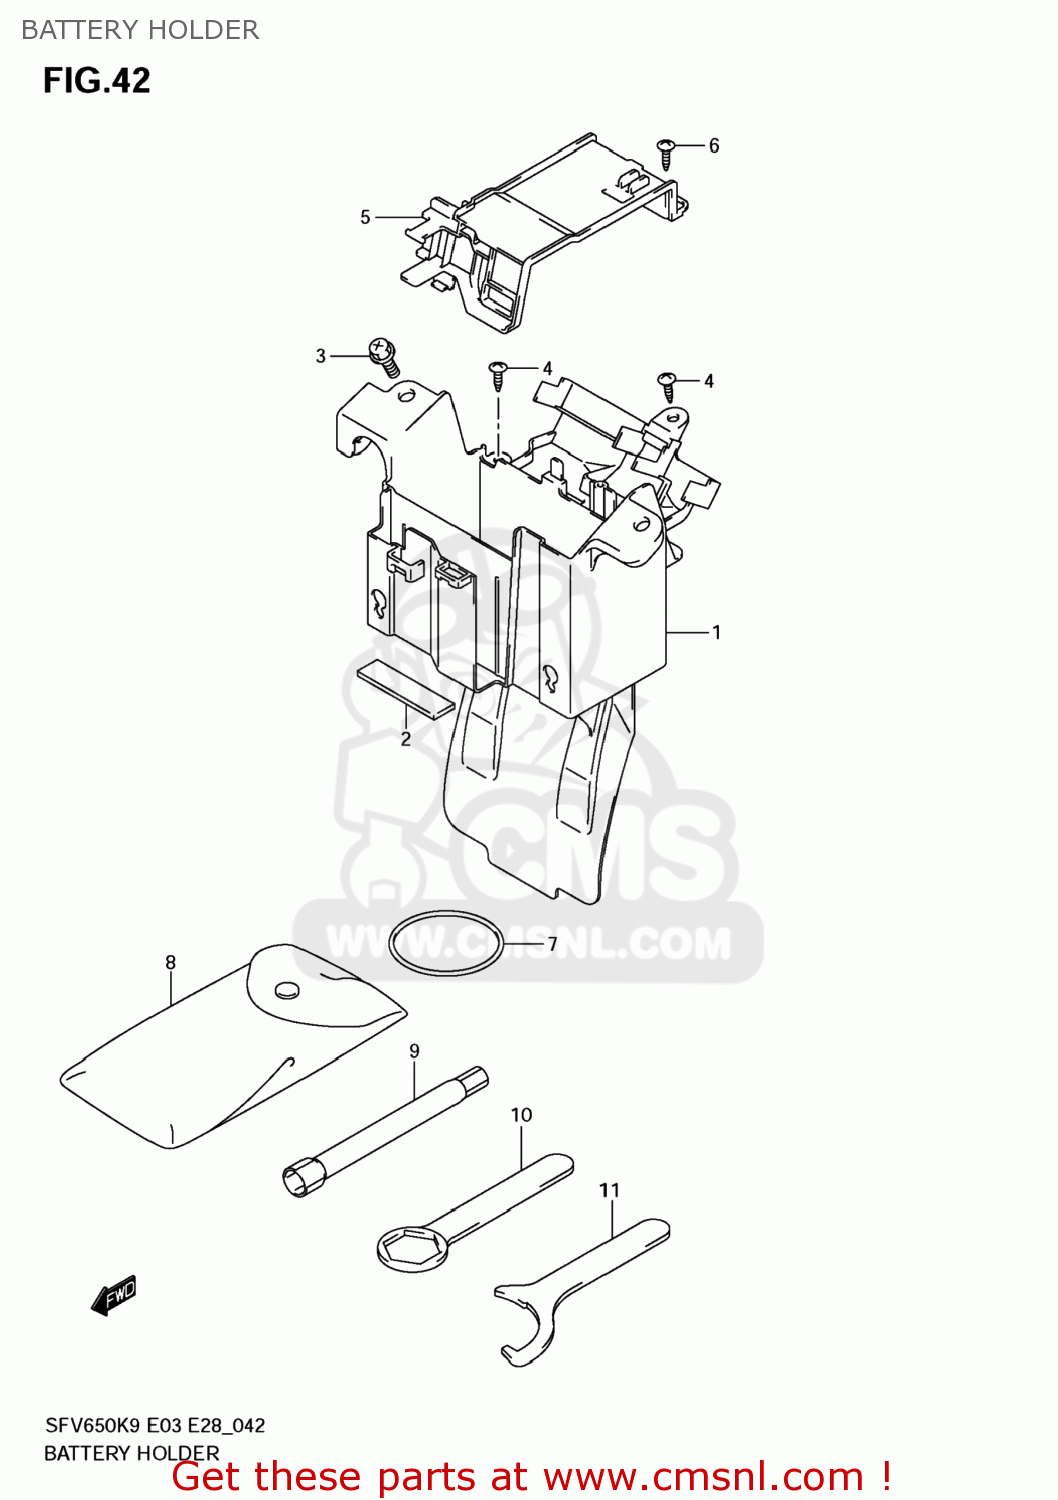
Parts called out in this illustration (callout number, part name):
1	HOLDER,BATTERY
2	CUSHION,FR FENDER
3	BOLT(6X16)
4	SCREW
5	LID,BATTERY HOLDER
6	SCREW
7	O RING(D:3.5,ID:61)
8	TOOL ASSY
9	SPARK PLUG WRENCH
10	RING SPANNER
11	CLAMP
